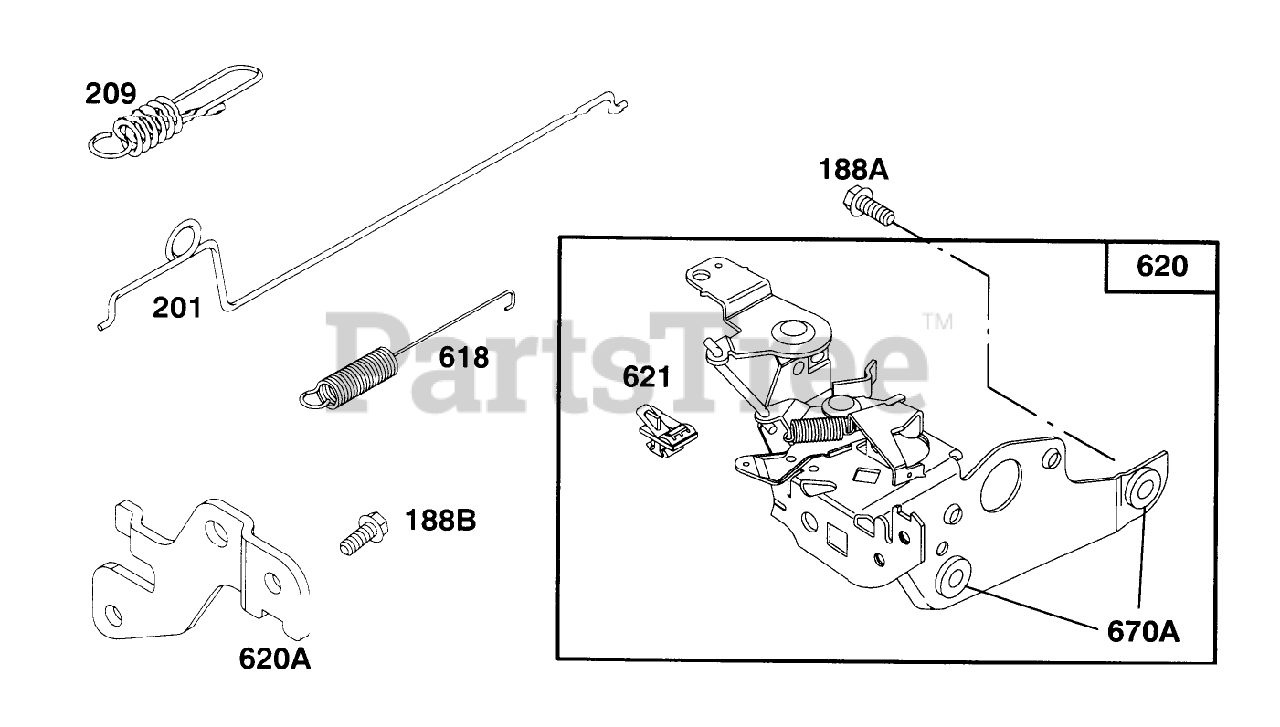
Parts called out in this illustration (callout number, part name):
188A	Screw-Hex.
188B	Screw-Hex.
201	Link-Govemor
209	Spring-Govemor
618	Spring-Choke
620	Bracket-Carburetor
621	Switch
670A	Spacer
